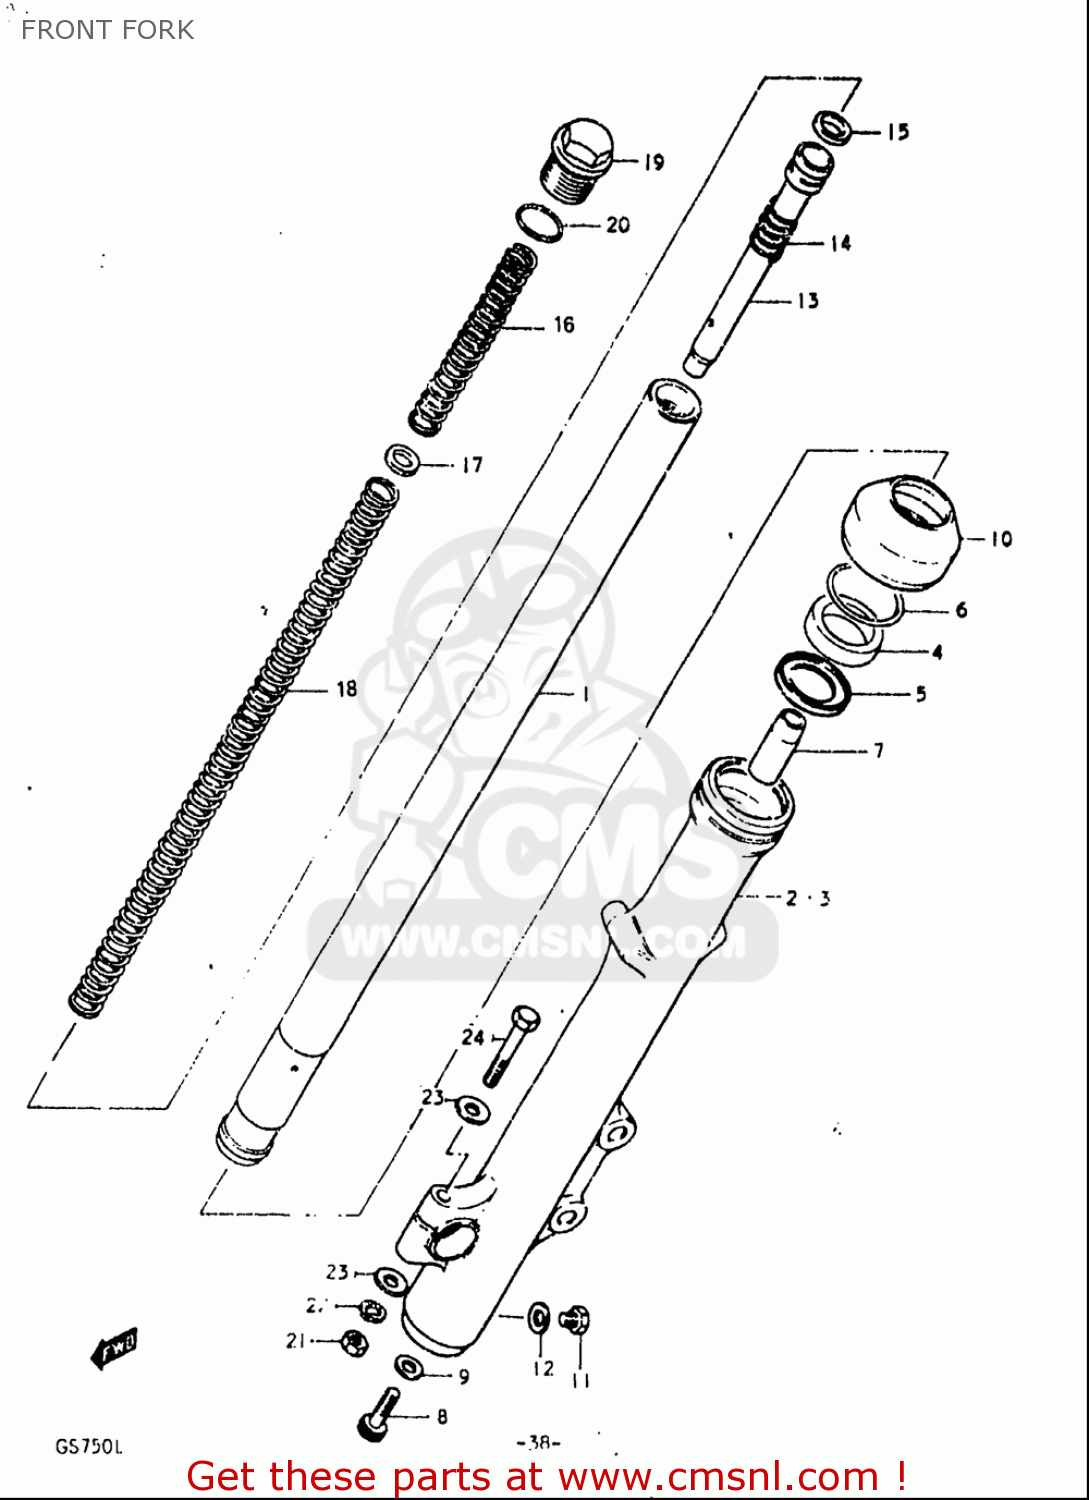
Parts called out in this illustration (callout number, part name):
4	SEAL,OIL
6	RING,OIL SEAL STOPPER
7	PIECE,OIL LOCK
8	BOLT(8X27)
9	GASKET (NAS)
10	DUST SEAL
11	BOLT
12	GASKET,DRAIN,PLUG (NAS)
15	RING,PISTON
20	O RING
21	NUT
22	WASHER,LOCK
23	WASHER
24	BOLT
